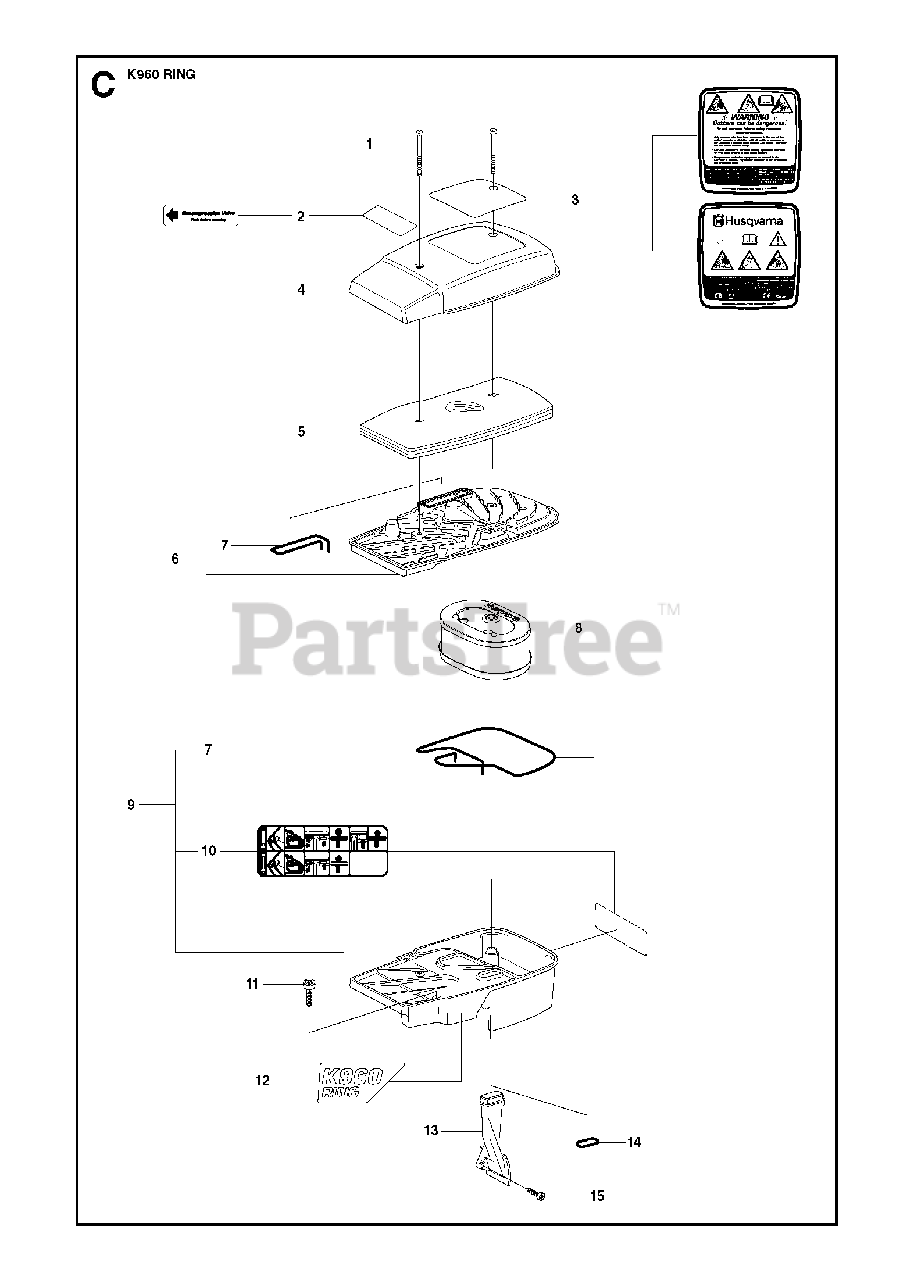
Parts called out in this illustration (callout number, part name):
1	SCREW ITXSCM
3	LABELEPA USA
3	LABEL
4	COVER
6	FILTER BOTTOMIncl. 7
7	SEALINGL=1,2 M. Cut to fit
9	CYLINDER COVER ASSYIncl. 7, 10
11	SCREW ITXSCM
15	SCREW ITXSCM
